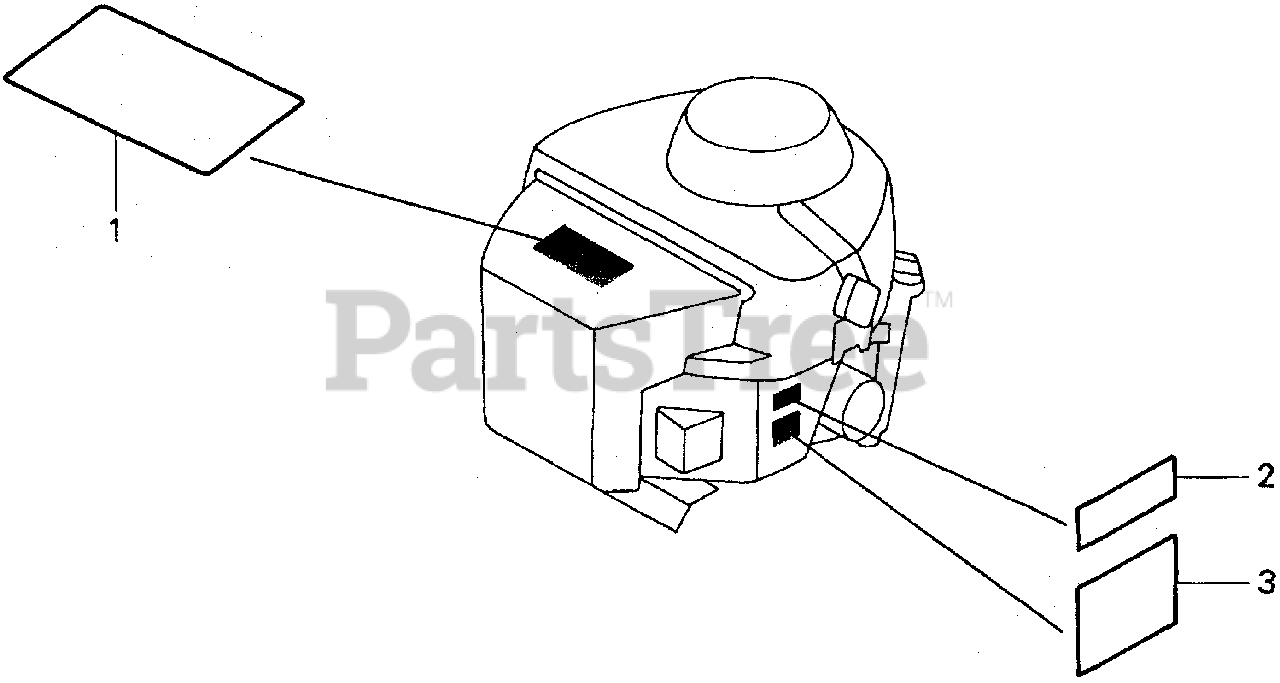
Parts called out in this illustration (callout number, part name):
1	MARK, EMBLEM (GXV610)
2	LABEL, SPECIFICATION (GXV610)
3	LABEL, CAUTION
